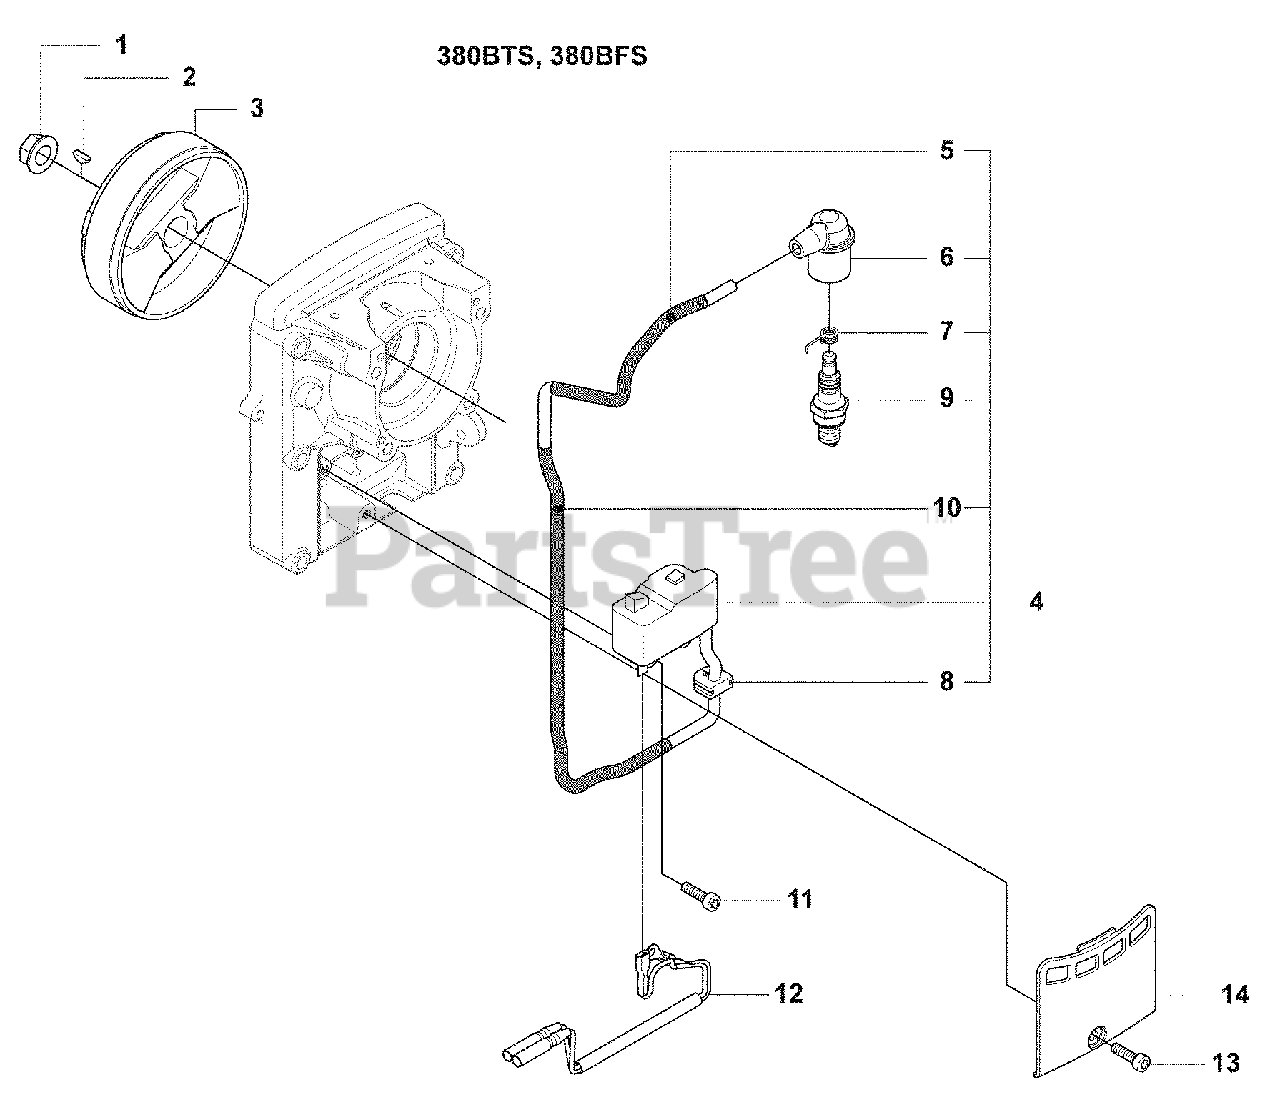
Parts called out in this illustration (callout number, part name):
1	Nut
2	Flywheel Key
4	Ignition Coil
6	Cap
9	Spark Plug, CMR7H BLYB
11	Torx Bolt, M4 X L16
13	Torx Bolt, M4 X L16
